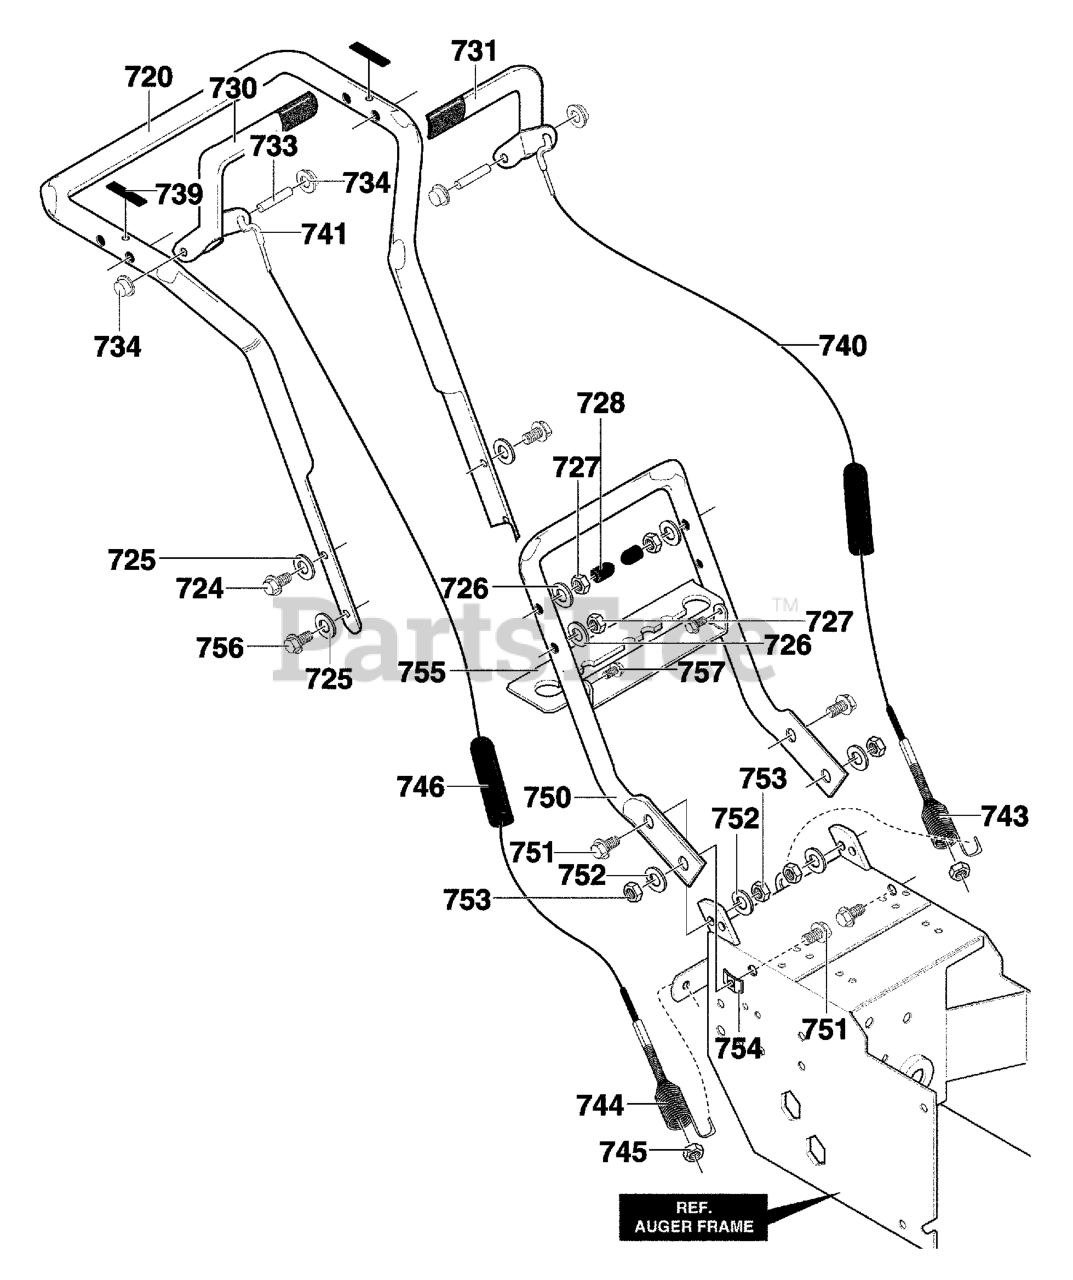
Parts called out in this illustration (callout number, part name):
720	HANDLE, UPPER
724	SCREW, 5/16-18 x 2.75
725	WASHER, FLAT .349X.69X.066
726	WASHER, SPTLK .31X.58X.08
727	NUT, 5/16-18 REGHEX
728	STOP, RED PLASTIC
730	CLUTCH HANDLE RH
731	CLUTCH HANDLE LH
733	PIN, CLUTCH HANDLE
734	NUT, PUSH ON CAP
739	BUMPER, RECTANGLE
740	CABLE, CLUTCH 28.44L
741	CABLE, AUGER CLUTCH
743	TENSION SPRING
744	SPRING, AUGER CLUTCH
745	NUT, 1/4-20
746	BOOT, CLUTCH SPRING
750	HANDLE, LOWER
751	CAPSCREW, Hex Head, 5/16-18 x 1
752	WASHER, SPTLK
753	NUT, 5/16-18 REGHEX
754	PUSHNUT, 5/16 BOLT RETAINER
755	BRKT, GEAR SELECTOR
756	SCREW, 5/16-18 x 2.00
757	SCREW, .25X.75X.51
